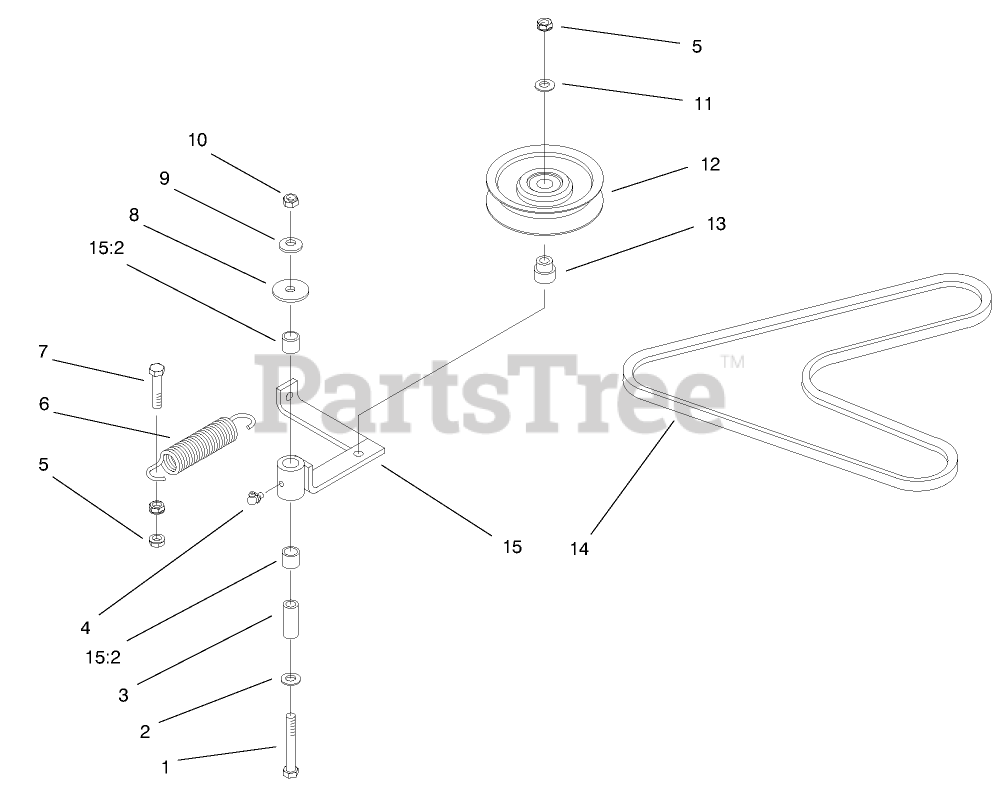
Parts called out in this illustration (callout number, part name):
1	SCREW-HH
2	WASHER-FLAT
3	Bushing
4	Zerk-Grease
5	NUT-HHF, WHIZ
6	Spring-Extension
7	SCREW-HH
8	Washer
9	Washer
10	NUT-LOCK, NI
11	WASHER-FLAT
12	Pulley-Idler
13	Bushing
14	Belt, Pump Drive
15	Idler Arm w/Bushings,Zerk
15:2	Bearing-Pivot
